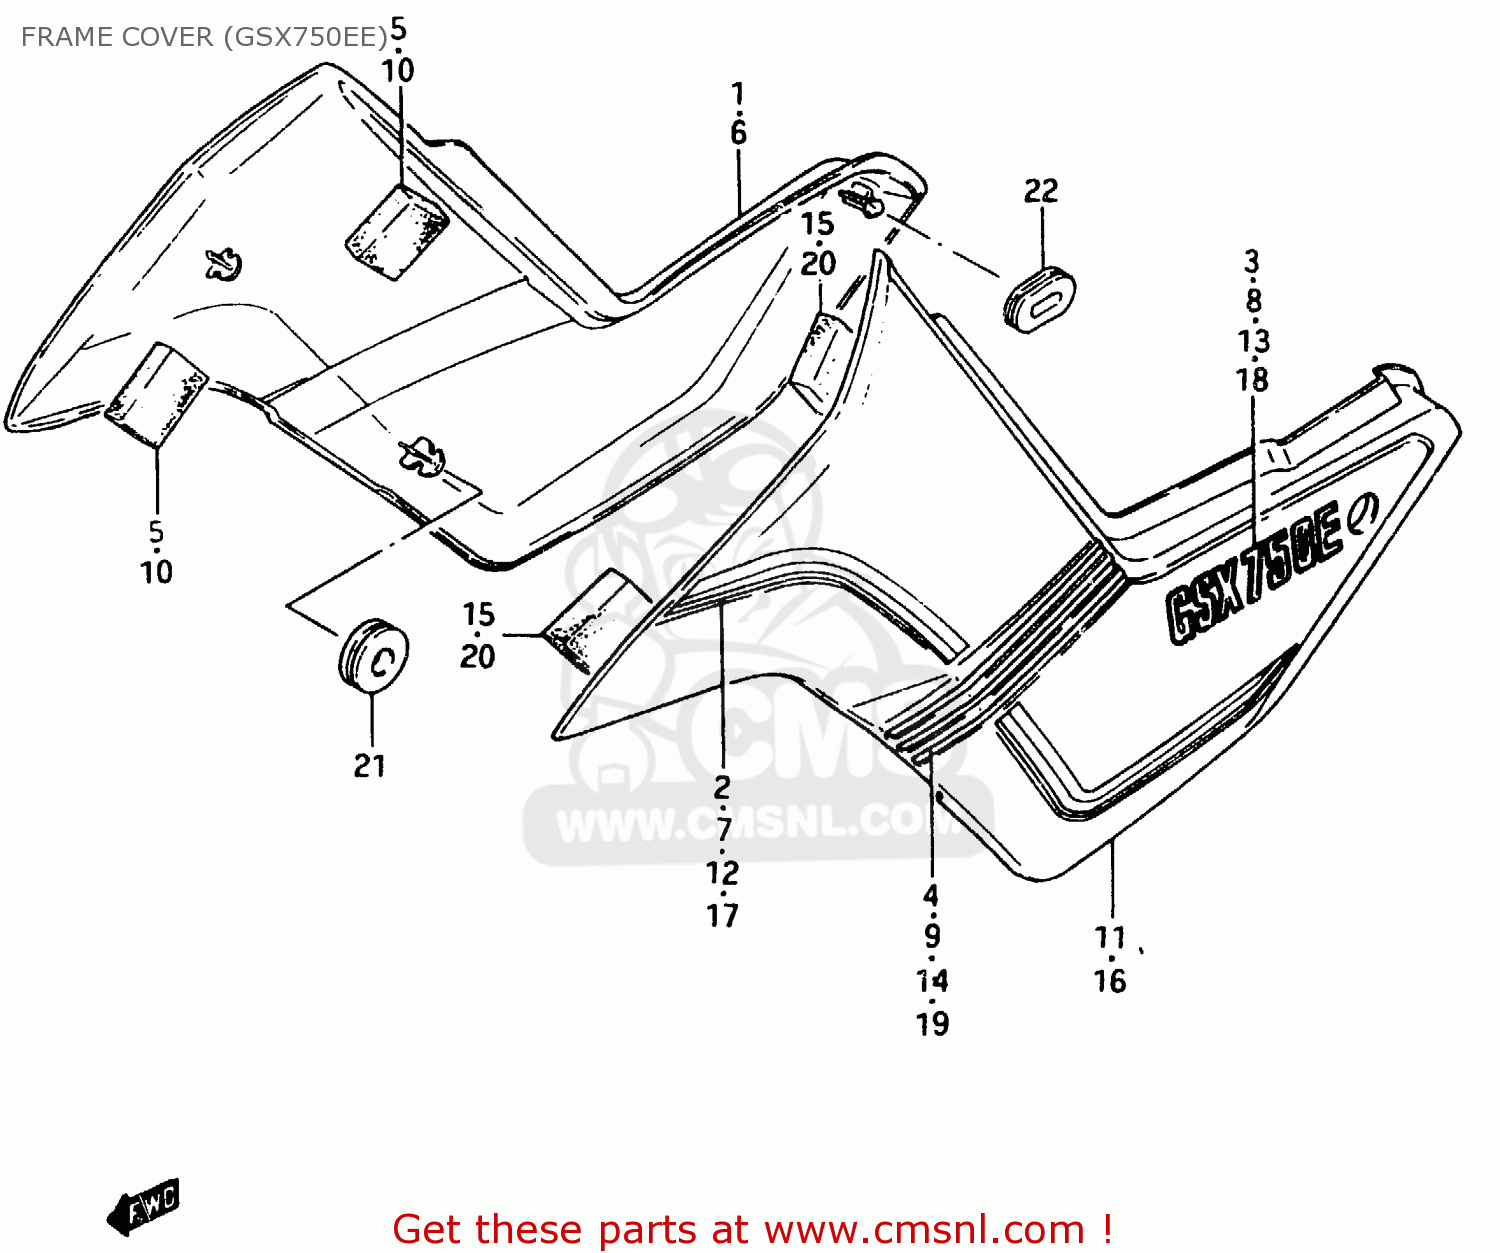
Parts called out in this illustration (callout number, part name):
1	COVER, FRAME RH (BLUE)
2	TAPE SET, FRAME COVER RH
3	EMBLEM
4	DENT,FRAME COVER,RIGHT
5	CUSHION
6	COVER, FRAME RH
7	TAPE SET, FRAME COVER RH
8	EMBLEM
9	DENT,FRAME COVER,RIGHT
10	CUSHION
11	COVER, FRAME LH (BLUE)
12	TAPE SET, FRAME COVER LH
13	EMBLEM
14	DENT,FRAME COVER,LEFT
15	CUSHION
16	COVER, FRAME LH (RED)
17	TAPE SET, FRAME COVER LH
18	EMBLEM
19	DENT,FRAME COVER,LEFT
20	CUSHION
21	CUSHION
22	CUSHION
